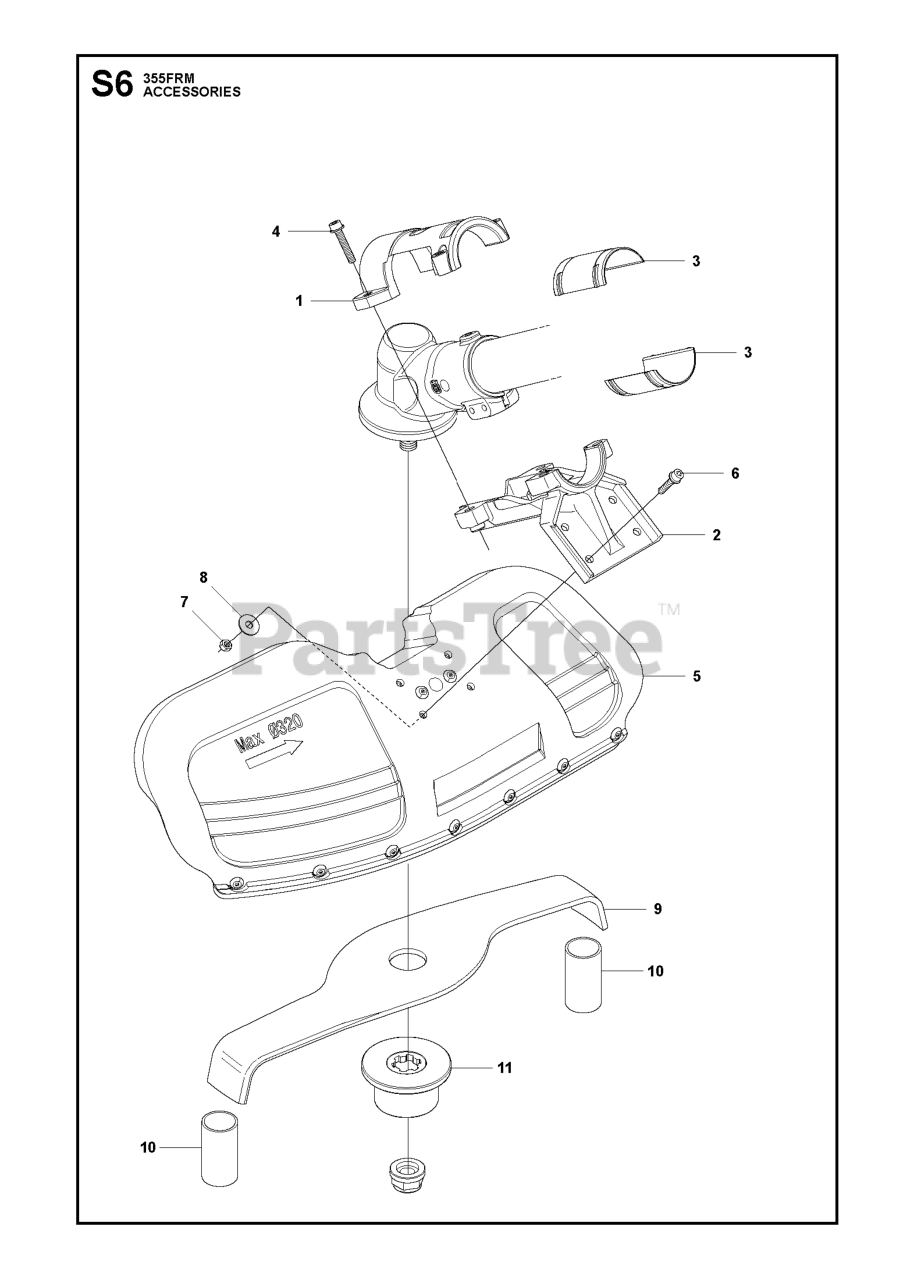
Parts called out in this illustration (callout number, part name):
6	SPRAY GUARD ASSY
8	LOCKNUT M5
11	TRANSPORT GUARD
